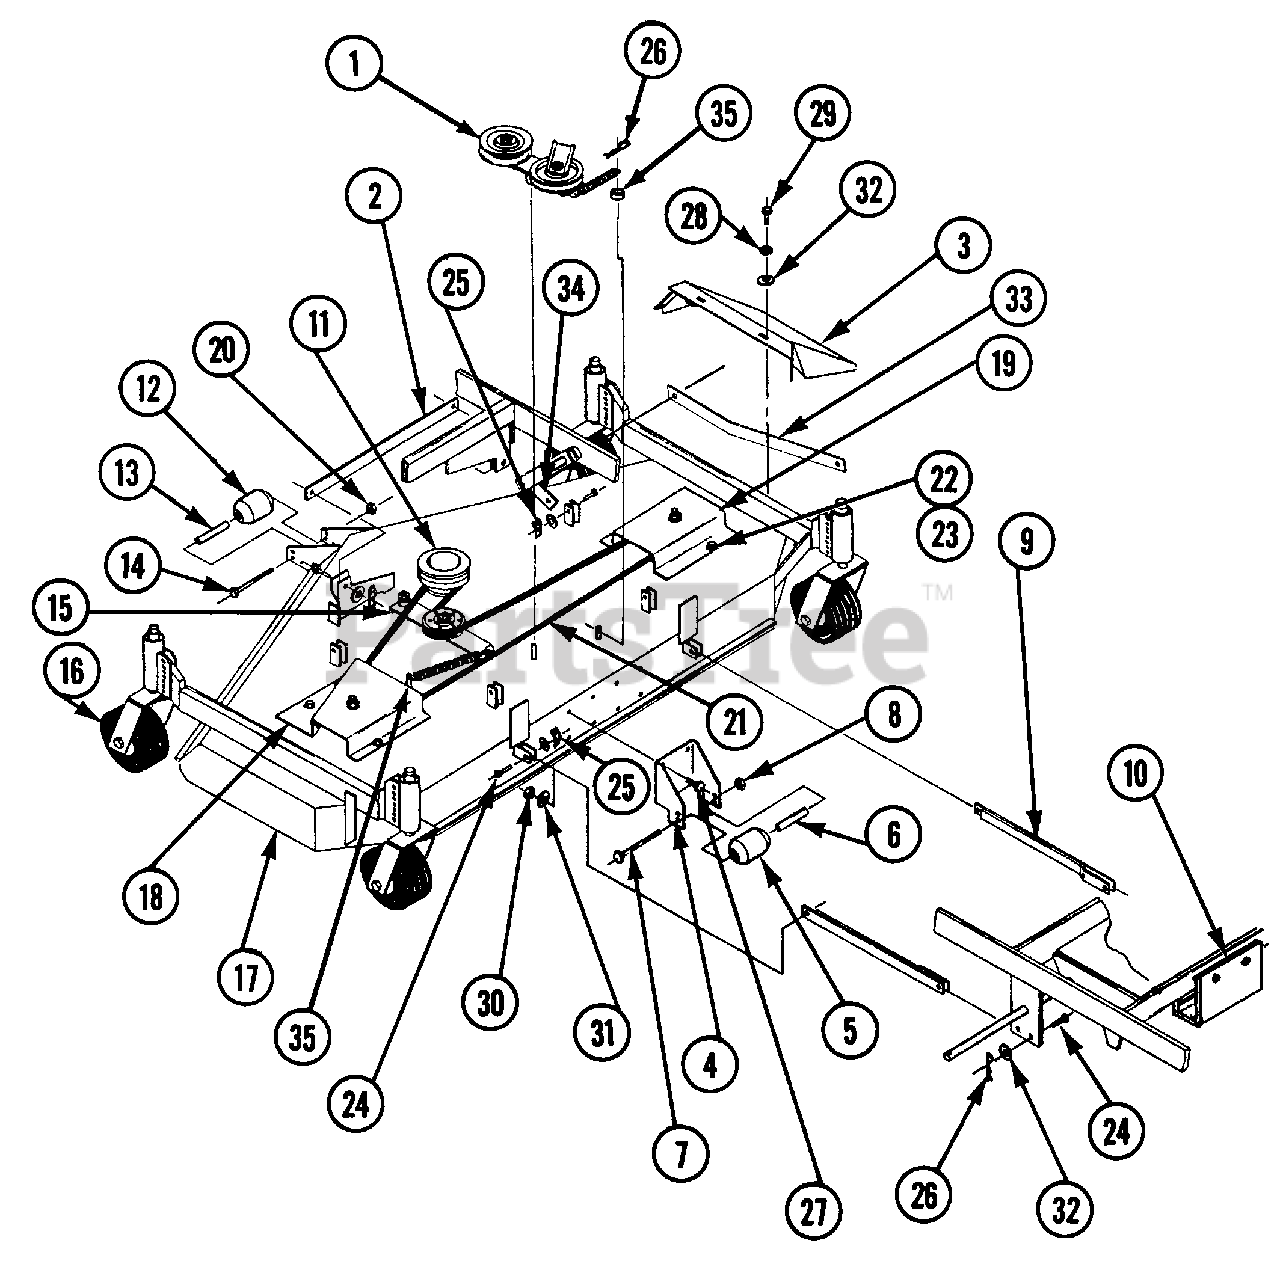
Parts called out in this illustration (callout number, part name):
1	DOUBLE IDLER ASSEMBLY
2	LATERAL BRACE
3	GRASS CHUTE ASSEMBLY
4	REAR SCALPER BRACKET
5	ANTISCALPER ROLLER
6	ROLLER SPACER BUSHING
7	CAPSCREW, HEX 3/8-16 X 4-1/2, GRADE 5
8	LOCKNUT, HEX 3/8-16 UNC
9	DRAG BAR WELDMENT
10	CLUTCH STOP GUARD
11	SPINDLE ASSEMBLY
12	ANTISCALPER ROLLER
13	ROLLER SPACER BUSHING
14	CAPSCREW, HEX 3/8-16 X 4-1/2 GRADE 5
15	SINGLE IDLER ASSEMBLY
16	GAUGE WHEEL ASSEMBLY
17	DECK WELDMENT (60")
18	LEFT PULLEY COVER
19	RIGHT PULLEY COVER
20	LOCKNUT, HEX 3/8-16 UNC
21	BELT, A-112
22	LOCKWASHER, 1/4, SPLIT SPRING
23	CAPSCREW, HEX, 1/4-20 X 3/4, GRADE 5
24	PIN, CLEVIS, 5/16 x 1-1/4
25	COTTER, RUE RING, 5/16 - 3/8 PIN
26	PIN, HAIR SPRING, .080 X 1-9/16
27	CAPSCREW, HEX, 3/8-16 X 7/8, GRADE 5
28	LOCKWASHER, 5/16, HEAVY SPRING
29	CAPSCREW, HEX, 5/16-18 X 3/4, GRADE 5
30	LOCKNUT, HEX, 3/8-16 W/ NYLOC
31	WASHER, 3/8 STD, FLATS W SERIES
32	WASHER, 5/16 STD, FLATS W SERIES
33	DECK CONNECTOR BAR
34	DECK ADJUSTMENT BAR
35	SPRING SPACER
